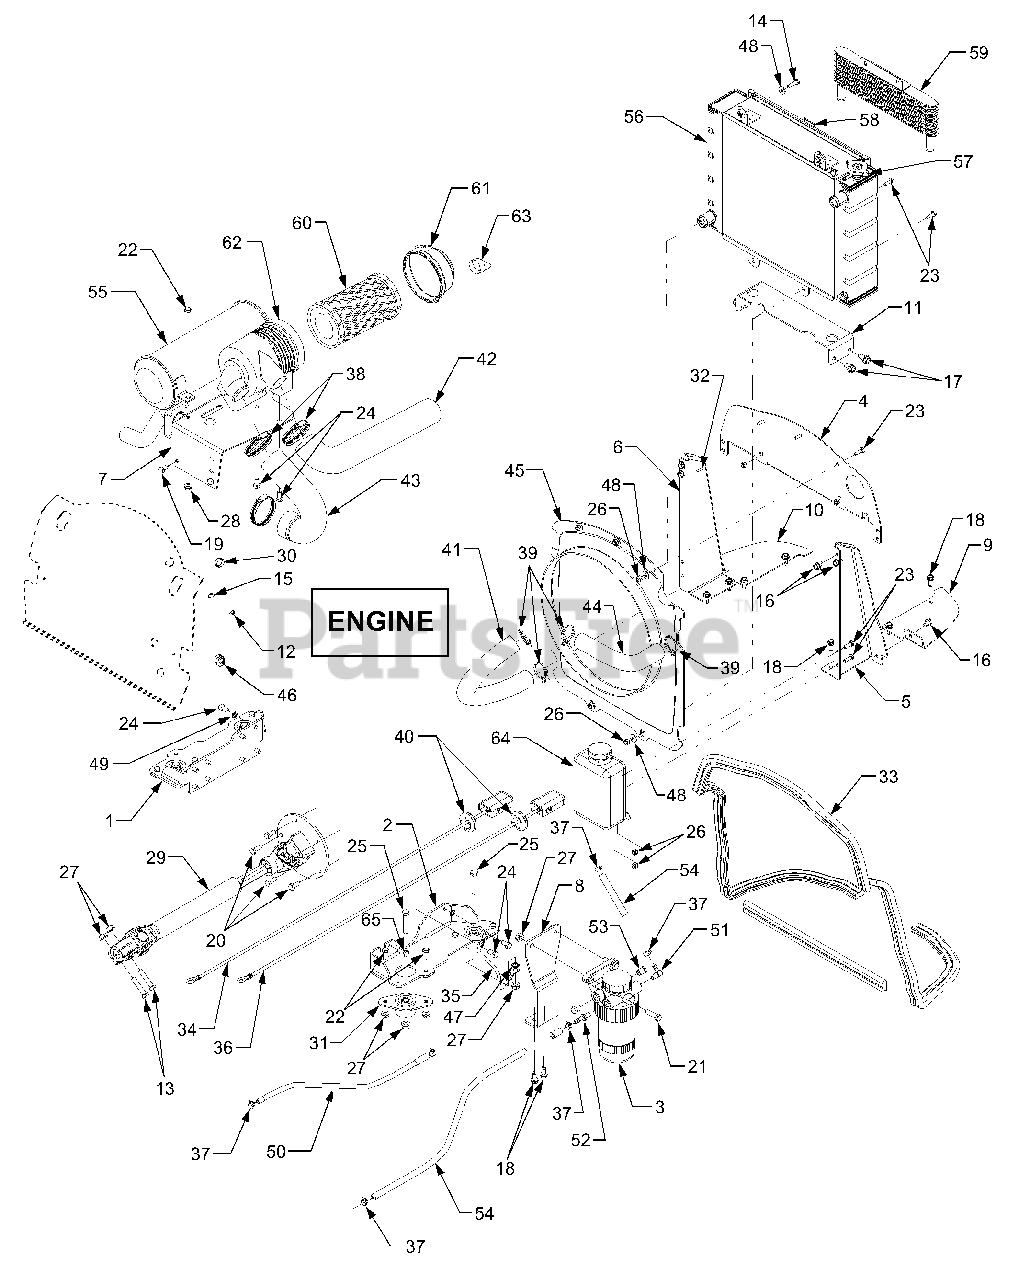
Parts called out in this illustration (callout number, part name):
1	Bracket, Engine LH
2	Bracket, Engine RH
3	Filter Assembly, Fuel
4	Plate, Radiator Baffle
5	Bracket, Radiator Mtg. RH
6	Bracket, Radiator Mtg. LH
7	Bracket, Muffler Mtg
10	Plate, Baffle, LH
11	Bracket, Radiator Mtg.
12	Screw, Hex Wash Hd Tapp 10-16 x .5
13	Screw, Hex Cap 3/8-16 x 1.75 GR5
14	Screw, Hex Cap 1/4-20 x 1.0 GR5
15	Screw, Hex Wash Hd Tapp 1/4-20 x .5
16	Screw, Hex Wash Hd Tapp 5/16-18 x .5
17	Screw, Hex Wash Hd Tapp 3/8-16 x .75
18	Screw, Hex Wash Hd Tapp 5/16-18 x .75
19	Screw, Hex Cap, M8-1.25 x 16
20	Screw, Hex Cap, M8-1.25 x 20
21	Screw, Hex Cap, 3/8-16 x 1/25 GR5
22	Screw, Hex Cap 5/16-18 x .75 GR5
23	Screw, Hex Cap 1/4-20 x .75 GR5
24	Screw, Hex Cap,I M8-1.25 x 16
25	Screw, Hex Cap 3/8-16 x 2/0 GR5
26	Nut, Hex Insert Lock, 1/4-20
27	Nut, Hex Flange Lock, 3/8-16
28	Nut, Hex Flange Lock, 5/16-18
29	Shaft, Drive
30	Plug, Cap
31	Mount, Neoprene Engine
32	Tape, Foam, .625 wide
33	Seal, Heat Baffle
34	Wire, Battery Pos.
35	Wire, Ground
36	Wire, Battery Neg
37	Clamp, Hose
38	Clamp, Adjustable Hose
39	Clamp, Hose
40	Grommet, Hose Guard
41	Hose, Radiator to Engine
42	Hose, Air Filter
43	Hose, Air Inlet
44	Hose, Engine to Radiator
45	Shroud, Fan
46	Grommet, Rubber
47	Washer, External Lock, 3/8
48	Washer, Flat, .28 x .74 x .063
49	Washer, External Lock, 5/16
50	Hose, Fuel Line
51	Fitting, 90 Degree Hose
52	Fitting, Straight Hose
53	Plug, Drain
54	Fuel Line, 5/16 ID
55	Muffler, Engine
57	Cap, Radiator, 13psi
58	Screen, Debris
59	Cooler, Oil
60	Element, Air Cleaner
61	Cap, Air Cleaner
62	Cannister, Air Cleaner
63	Nozzle, Air Cleaner
64	Bottle, Overflow
65	Screw, Hx Cap, M8-1.25:25 GR8
